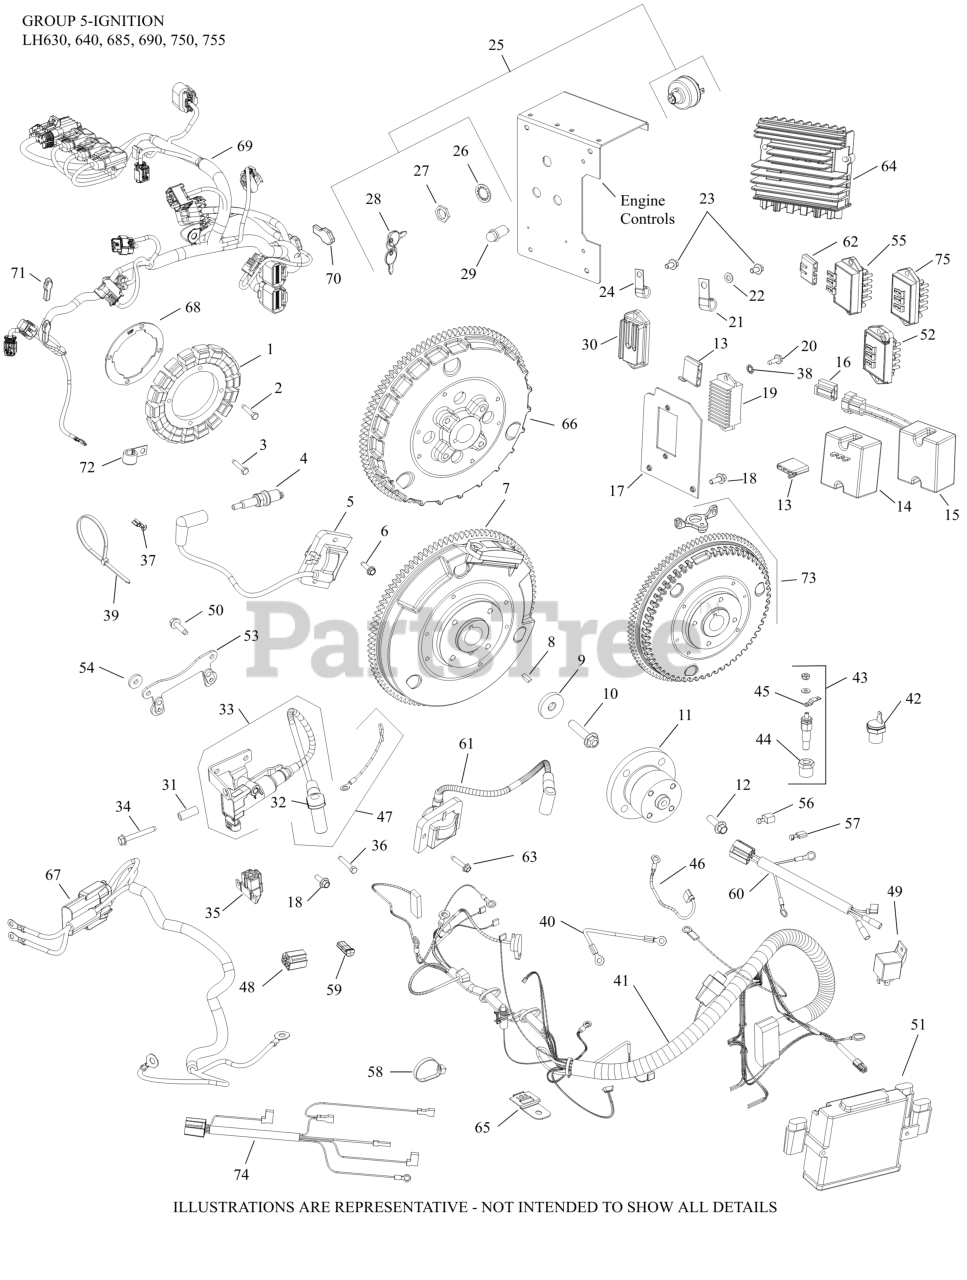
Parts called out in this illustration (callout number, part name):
1	KIT, 15 / 20 AMP STATOR
2	SCREW, THREAD FORMING
4	SPARK PLUG
7	FLYWHEEL, ASSEMBLY
8	KEY, 3/16" X 5/8"
9	WASHER, FLAT 13/32"
10	SCREW, FLG M10X1.5X45-USE 25 086 361-S
13	CONNECTOR
21	CLIP, CABLE
22	WASHER, FLAT 1/4" (O.D. 1/2")
35	CONNECTOR
40	KIT, GROUND, LEAD
41	HARNESS, WIRING
46	LEAD, 20/25 AMP B+
52	REGULATOR, RECTIFIER
61	MODULE, IGNITION
63	SCREW, THREAD FORMING
72	CLIP, CABLE (KM)
